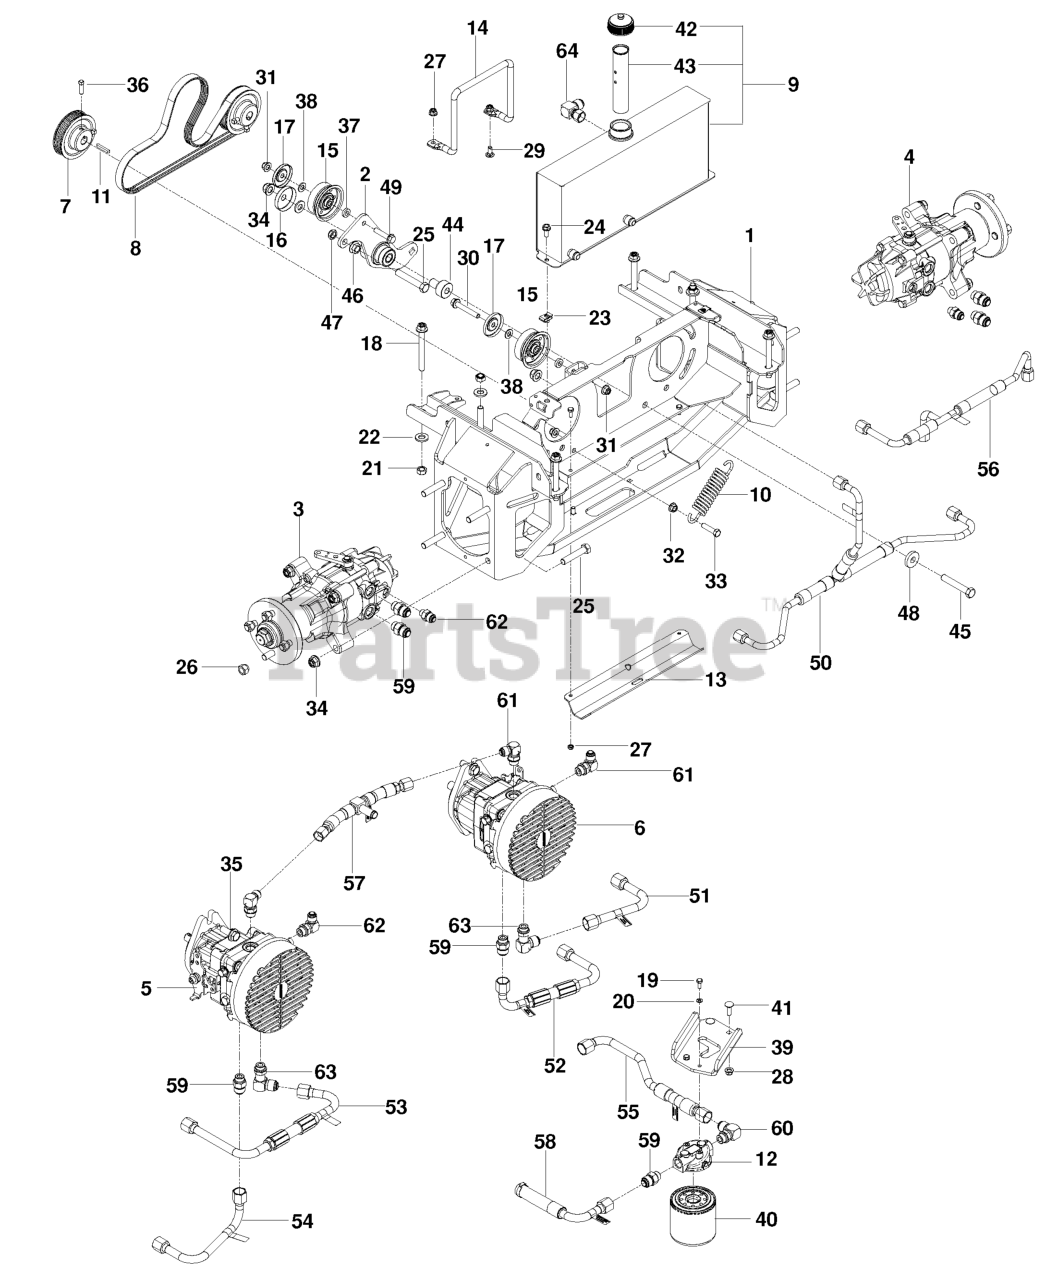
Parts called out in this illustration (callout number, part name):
1	WELDMENT, PUMP BAY, BLK
2	ASSEMBLY.IDLER.W/BEARINGS
3	HG_MOTOR, PRM, RT
4	HG_MOTOR, PRM, LT
5	HG_PUMP, 21CC, RT
6	HG_PUMP, 21CC, LT
7	PUMP SHEAVE
8	BELT, PUMP
9	ASSEMBLY, RESERVOIR
11	KEY, METRIC
12	FILTER HEAD
13	GUARD, HOSE
14	GUIDE, BELT
15	PULLEY, IDLER
16	SHIELD, DUST
17	DUST SHIELD
18	BOLT 7/16 X 4 GR 8 BLK PHOS
19	HCS 1/4C X 5/8
20	LOCKWASHER 1/4"
21	7/16-14 HEX NUT W/NYL RING ZD
22	WASHER 1/2" FLAT
23	U-CLIP 5/16-18 NUT RETAINER
24	HHFS 5/16-18 X 3/4
25	HEX SCREW 1/2-13 X 2.5" GR 5
26	LUG NUT 1/2F
27	JAM NUT 1/4C (2 2 PW01)
28	5/16-18 NYLOC FLANGE NUT
29	BOLT 5/16C X 3/4" CARRIAGE
30	HHFS 3/8-16 X 2.5 GR 5 ZD
31	NUT 3/8-16 HEX FLG NYLOC ZD
32	NUT 3/8C WHIZ
33	HCS 3/8-16 X 1-1/2
34	NUT, 1/2-13 HEX FLG NYLOC ZD
35	HCS 1/2C X 1 1/4 SERRATED HEAD
36	SCREW 5/16C X 1 SQ HEAD SET
37	WASHER 3/8 X 3/4 X .187 TK
38	WASHER 3/8 SAE FLAT
39	MOUNT, FILTER, BLK
40	FILTER 25 MICRON
41	RHSNB 5/16C X 1
42	CAP, HYDRAULIC
43	TUBE, ANTI-SPLASH
44	PIVOT, BEARING
45	SCREW, 1/2C X 3 HEX CAP
46	NUT 1/2-13 HEX
47	NUT, HEX 1/2-13 THIN W/NY
48	WASHER .525 X 1.375 X .25
49	BLT 3/8-16X1-3/4 WHIZLK ZN SP
50	LINE, HYD, CASE-RM
51	LINE, HYD, LT-AA
52	LINE, HYD, LT-BB
53	LINE, HYD, RT-AB
54	LINE, HYD, RT-BA
55	LINE, HYD, SUCTION
56	LINE, HYD, PUMP
57	LINE, HYD, CHARGE
58	LINE, HYD, CHARGE
59	FITTING, 10-8 STRAIGHT
61	ELBOW, 90 DEGREE
62	FITTING, HYDRO
63	FITTING, 10-8 90 DEG
64	FITTING, HYD, 6500-10-8
